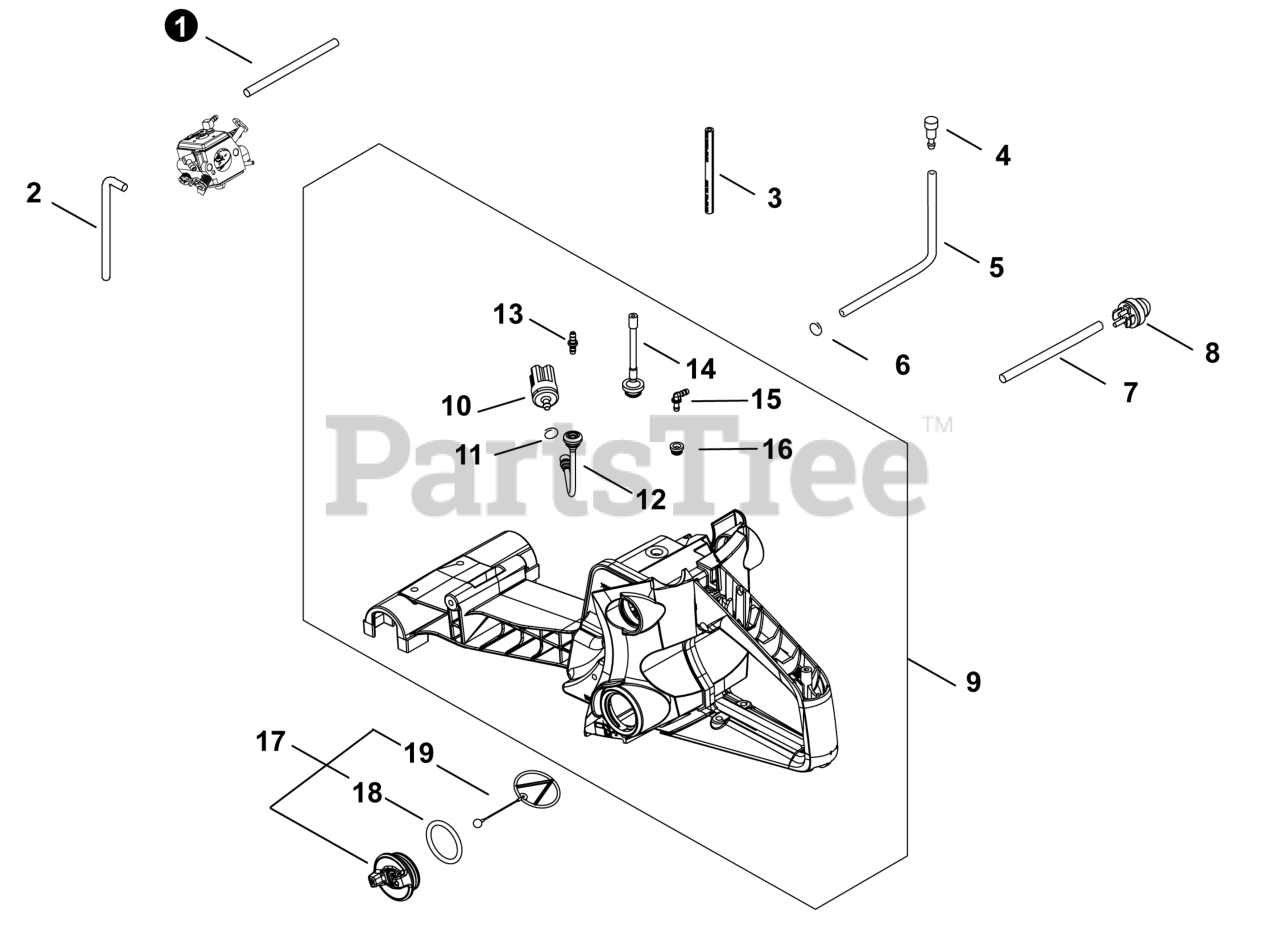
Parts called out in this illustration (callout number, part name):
1	PIPE, PULSE
2	PIPE, PULSE
3	PIPE, FUEL 3×6×75
4	VENT ASSY
5	PIPE, FUEL 3×5×255
7	PIPE, FUEL
8	BULB, PURGE
9	HANDLE ASSY, REAR
10	FILTER, FUEL
11	CLIP Ø6
12	PIPE, FUEL
13	CONNECTOR, PIPE
14	PIPE
15	CONNECTOR, PIPE
16	GROMMET, FUEL
17	CAP ASSY, FUEL
18	O-RING 29
19	FUEL CAP CONNECTOR (L=60MM)
